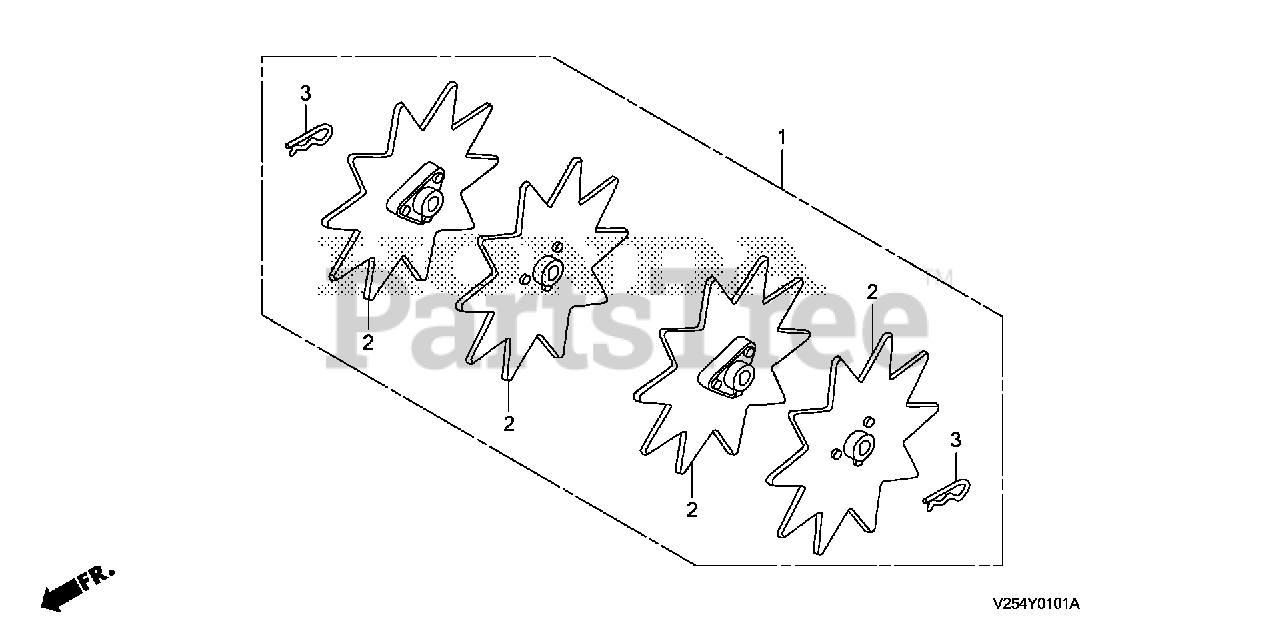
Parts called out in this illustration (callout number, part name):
1	AERATOR KIT
2	TINE, AERATOR
3	PIN, LOCK (17MM)
